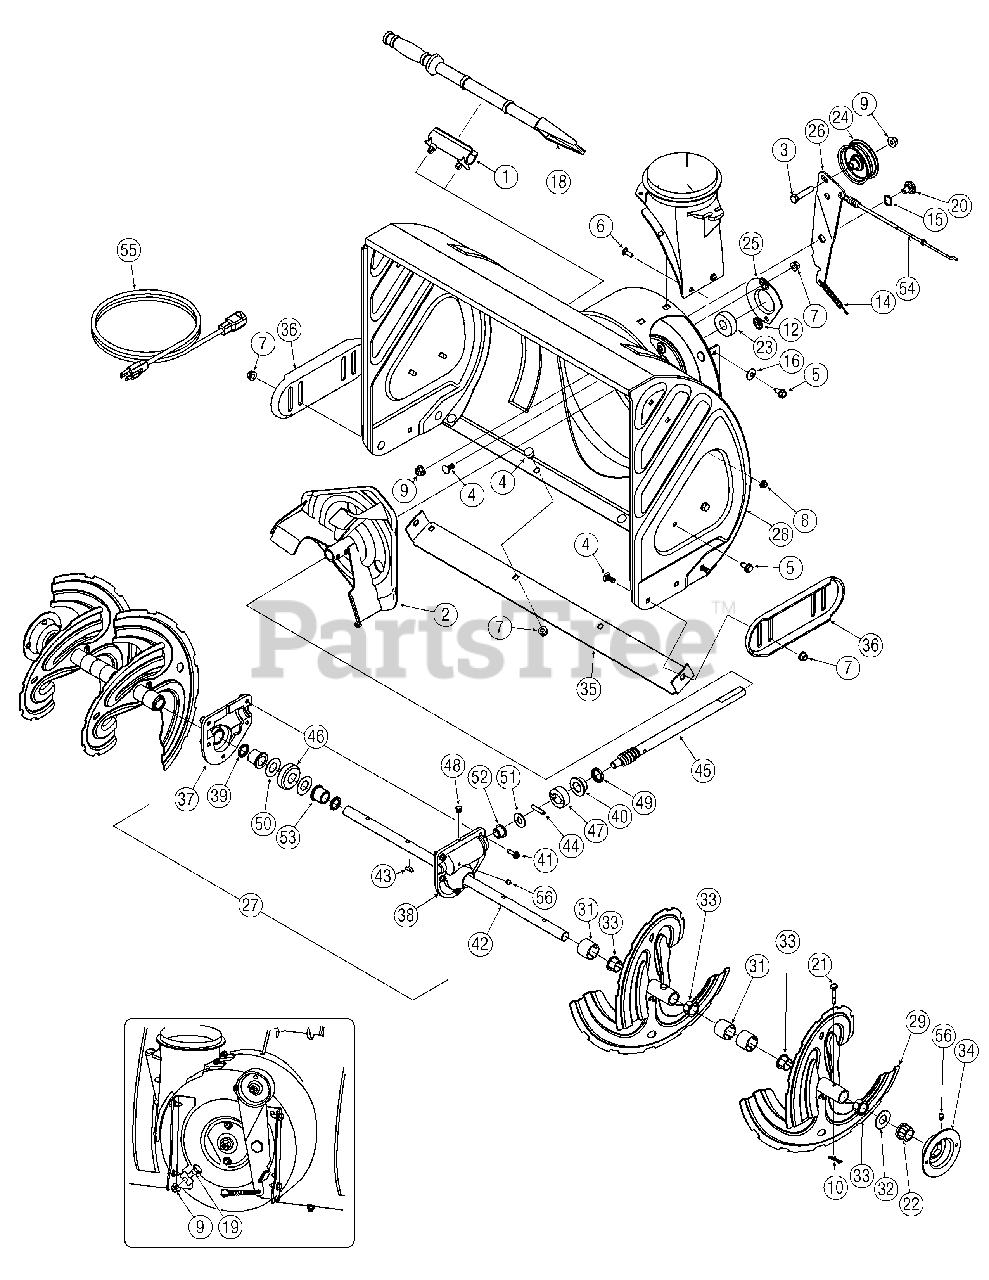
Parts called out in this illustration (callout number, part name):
1	Snow Removal Tool Mount
3	Hex Screw, 3/8-16, 1.75, Gr5
4	Bolt, Carriage, 5/16-18, .750 Gr1
5	Screw, 5/16-18, 0.625
6	Screw, Carriage, 1/4-20, .750, Gr5
7	Nut, Flange Lock, 5/16-18, Nylon
8	Nut, Flange Lock, 1/4-20, Nylon
9	Nut, Flange Lock, 3/8-16, Nylon
10	Cotter Pin, Bow-tie
11	Cable, Tie, 3/16 x .05 x 7.4
12	Nut, Push-on, .25 Dia
13	Chute, Adapter 5" Dia
14	Spring, Extension, .38 OD x 3.6
15	Washer, Wave, .625 x .885 x .015
16	Washer, Bell, .340 x .872 .060
17	Washer, Flat, .25 x .630 x .0515
18	Snow Removal Tool
19	Screw, Shoulder, .498 x .34, 3/8-16
20	Screw, Shoulder, .625 x .17, 3/8 -16
21	Shear Pin, .25 x 1.50
22	Bearing, Hex Flange x .75
23	Bearing, Ball, .75 ID x 1.85
24	Flat Pulley, Idler, 2.75 OD
25	Housing, Bearing, 1.85 ID
27	Gearbox Ass’y w/ Fitting, Auger
31	Spacer, 1.25 OD x .75 ID x 1.00
32	Washer, Flat, .76 x 1.49 x .06
33	Bushing, Flange, .80 ID x .91 OD
37	Housing, Auger, RH Reducer
38	Housing, Auger, LH Reducer
39	Seal, Oil, .750 ID
40	Bearing, Flange, .75 x 1.0 x.925
41	Screw, Self-tapping, 1/4-20, 0.750
42	Axle, Auger, 26"
43	Key, Hi-pro 3/16 x 5/8
44	Pin, Dowel, .25 OD x 1.2
45	Shaft, Worm .75 OD
46	Gear, Worm 20T
47	Collar, Thrust
48	Plug, 1/4 x .437
49	Seal, Oil, .75 x 1 x .131
50	Washer, Flat, .760 ID x 1.5 OD
51	Washer, Flat, .51 x 1.12
52	Bearing, Flange, .75 x 1.0 x.925
53	Bearing, Flange, .75 x 1.00 x .975
54	Clutch Cable, Auger, 47.23"
55	Extention Cord, 110V
56	Grease Fitting, 3/16"
